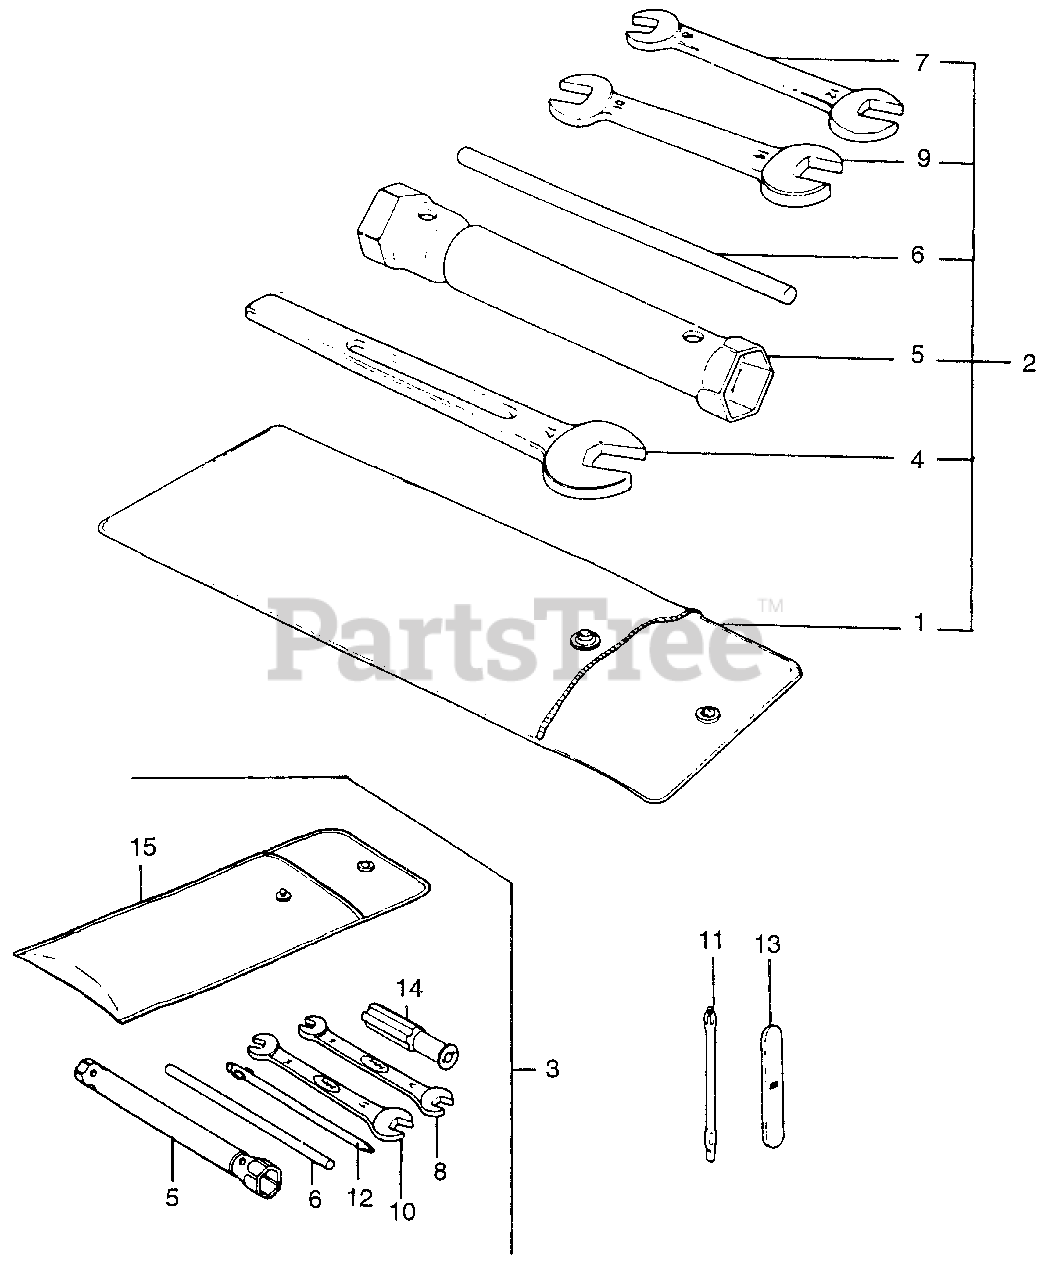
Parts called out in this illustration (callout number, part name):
2	TOOL ASSY.
4	WRENCH, OPEN END (7MM)
5	WRENCH, SPARK PLUG (NOT AVAILABLE)
6	HANDLE, BOX WRENCH
7	WRENCH (8X12) (OPEN END)
9	WRENCH (10X14) (OPEN END)
